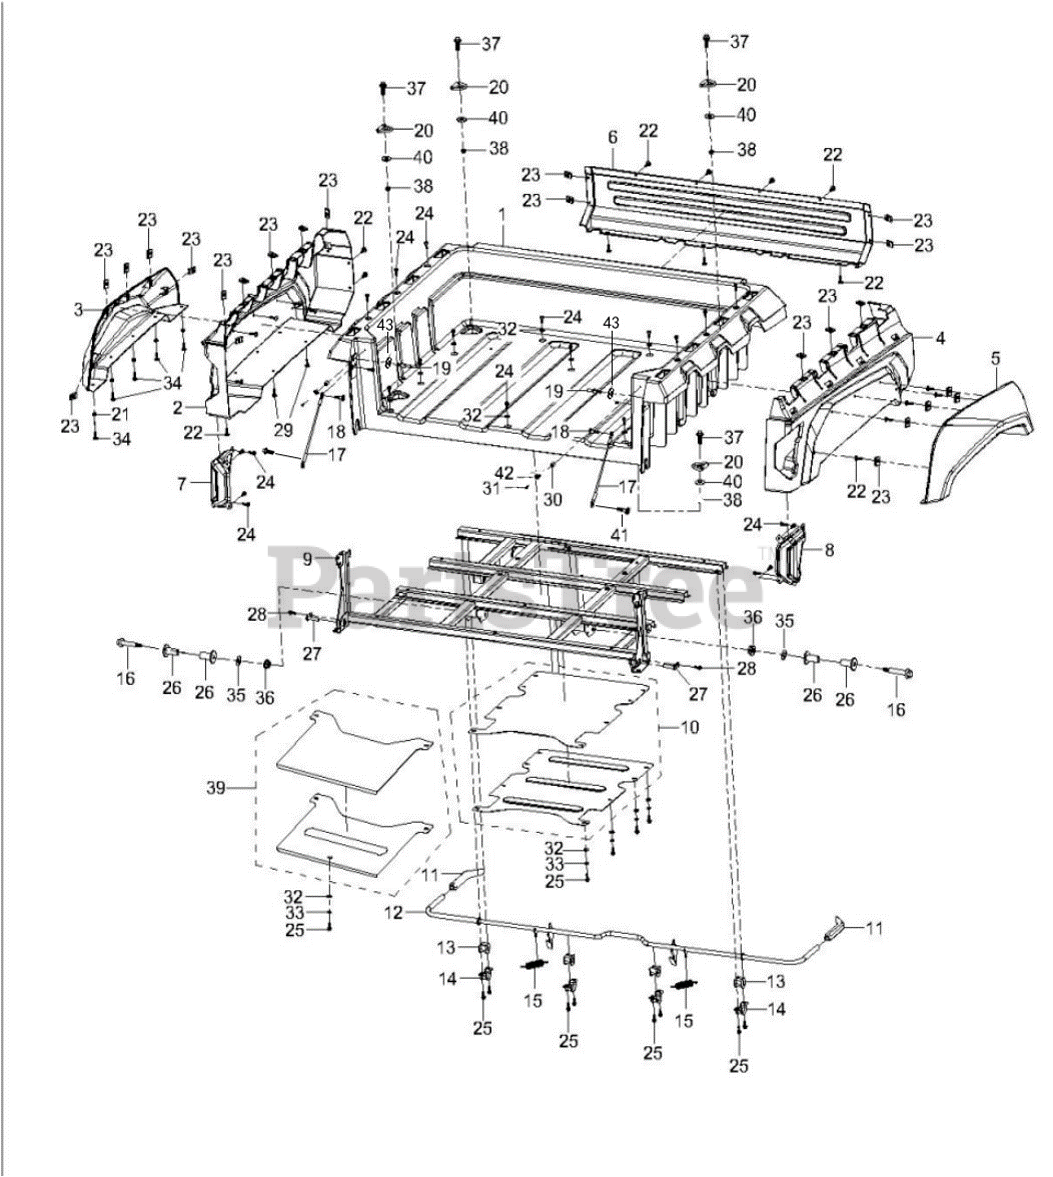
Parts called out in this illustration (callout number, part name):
2	CARGO BED SIDE PANEL LEFT RED
2	CARGO BED SIDE PANEL (LH) (YELLOW)
2	CARGO BED SIDE PANEL LEFT BLUE
2	CARGO BED SIDE PANEL LH BLACK
2	CARGO BED SIDE PANEL LEFT CAMO
3	FENDER - REAR LEFT TOP
4	CARGO BED SIDE PANEL RIGHT RED
4	CARGO BED SIDE PANEL (RH) (YELLOW)
4	CARGO BED SIDE PANEL RH BLUE
4	CARGO BED SIDE PANEL RH BLACK
4	CARGO BED SIDE PANEL RH CAMO
5	FENDER - REAR RIGHT TOP
6	FRONT CARGO BED PANEL
7	TAIL BRAKE LIGHT ASM REAR LEFT
8	TAIL BRAKE LIGHT ASM REAR RIGHT
10	HEAT PROTECTOR - CARGO BED
11	RELEASE LEVER GRIP
12	CARGO BED RELEASE LEVER KIT
13	RELEASE LEVER CUSHION
15	TENSION SPRING 2X14X40
16	PIN CARGO BED KIT
17	TAILGATE CABLE
18	SHOULDER BOLT M8X15-10X14.5
19	SHOULDER BOLT M8X15-10X10-53
19	SHOULDER BOLT
20	CARGO BED HOOK
21	HEX FLANG NUT M6
22	SCREW M6X16
23	CLAMP NUT M6X6
24	SOCKET HEX FLAT HEAD BOLT M6X16
25	HEXAGON FLANGE BOLT M6X16
26	BUSHING - PLASTIC 12X18
27	HINGE STRAP
28	HEX HEAD FLANGE BOLT M8X12
29	SCREW - CROSS HEAD SELF TAPPING
30	CARGO DOOR SHOCK ABSORBER
32	FLAT WASHER
33	SPRING WASHER
34	HEX HEAD CAP SCREW M6X16
36	LOCK NUT M8
37	HEX FLANGE BOLT M10-1.50X30
38	LOCK NUT M10X1.25
39	INSULATION PLATE II
40	WASHER - FLAT 10X28X2
41	BOLT M8X15-15X5
42	FLANGE BUSHING
43	SPRING WASHER-8
